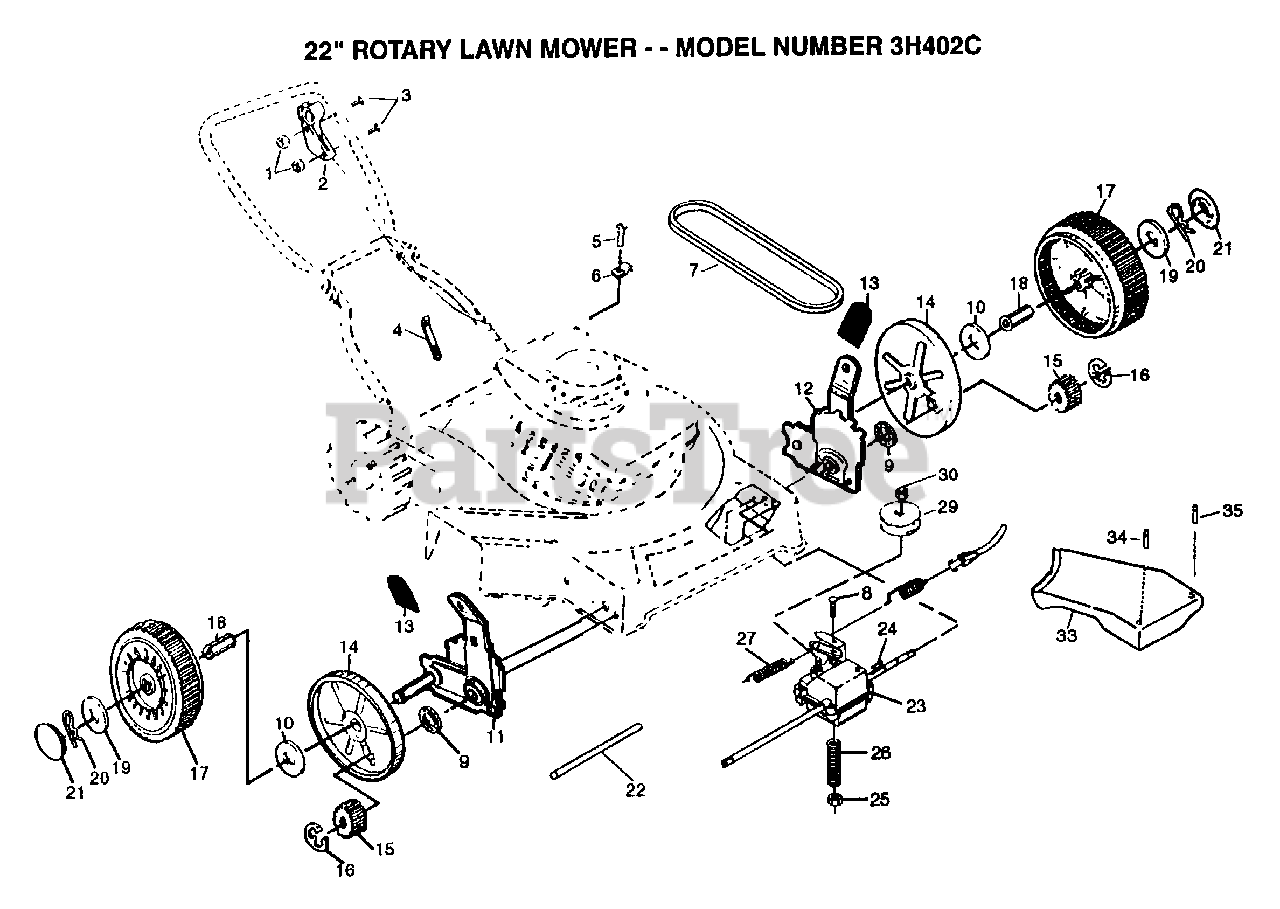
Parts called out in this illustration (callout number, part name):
1	LOCKNUT
2	CONTROL.DRIVE
3	SCREW
5	TAPPING SCREW
6	GUIDE CLIP PM
8	BOLT.1/4-20X2.0
9	WASHER PM
10	WASHER FLUT
13	KNOB PM
14	DUST SHROUD PM
15	PINION.GEAR
16	E-RING.7/16.RE.
17	WHEEL.8X2.LP.PR
18	BUSHING.ROUND
19	WASHER
20	RETAINER CLIP PM
21	HUB CAP
22	DRV SHAFT TUBE PM
24	HI PRO KEY
26	SPRING.TENSION
27	SPRING
29	PULLEY.DRIVEN
30	LOCKNUT
33	COVER DRIVE BLK
